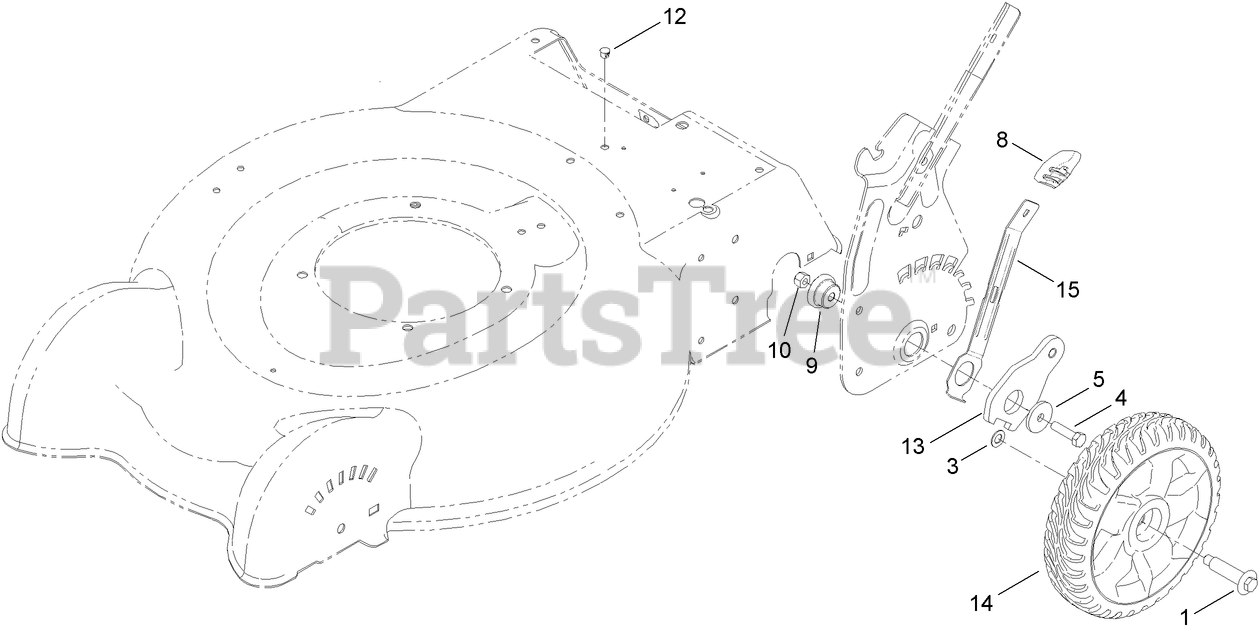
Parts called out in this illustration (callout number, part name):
1	BOLT-SHOULDER
4	SCREW-HH
5	WASHER-FLAT
8	KNOB-LEVER, HOC
9	BUSHING-MOUNT, HOC
10	NUT-LOCK, NI
12	PLUG-DOME
13	ARM-PIVOT, REAR (SERVICE)
14	11 INCH WHEEL ASM
15	ARM-SPRING, REAR
